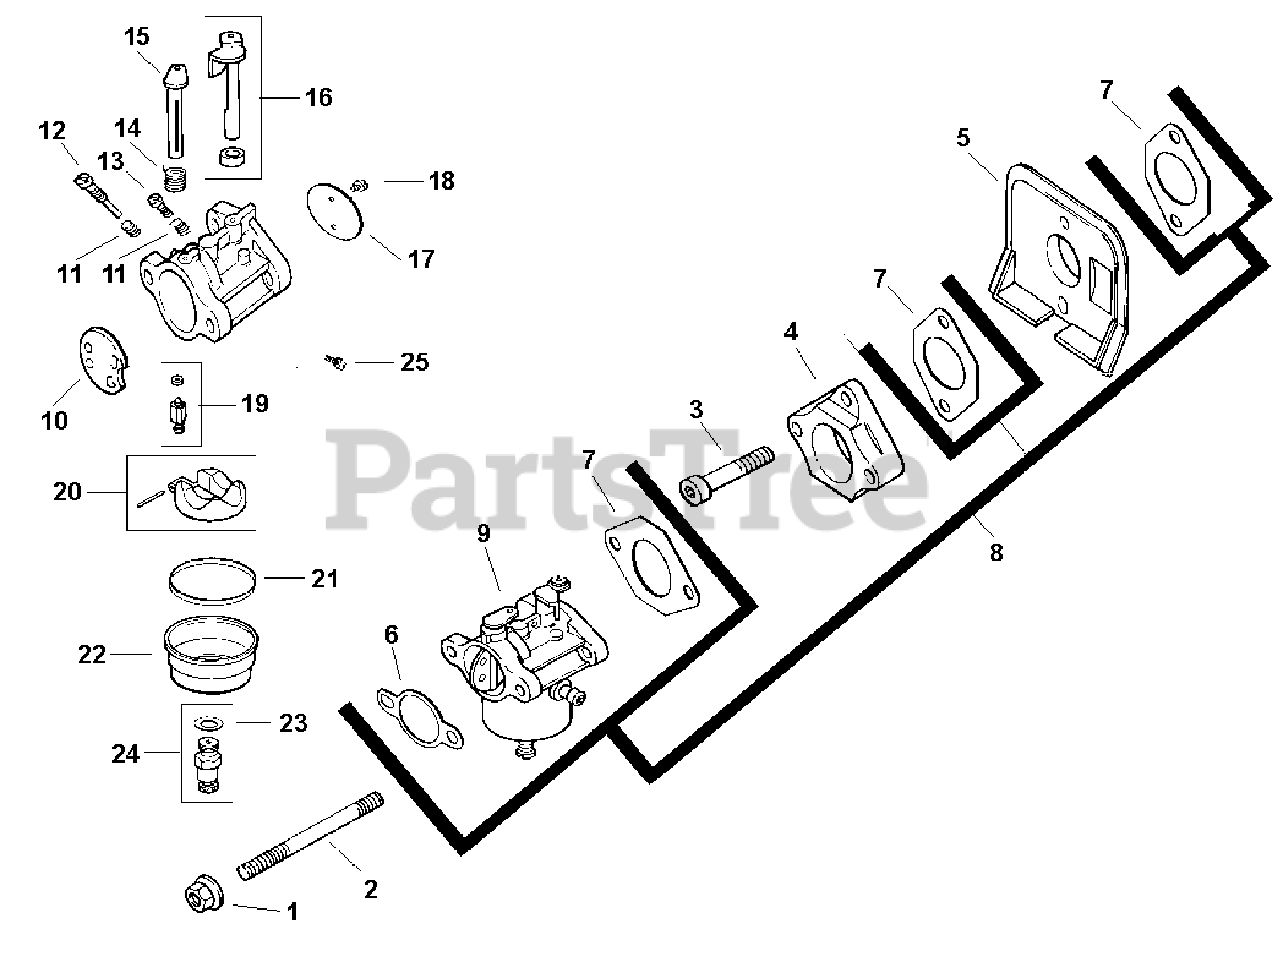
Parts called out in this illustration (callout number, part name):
1	Nut, hex. flange M6x1.0
2	Stud, carburetor M6x1x85
3	Screw, hex. socket cap M6x1x35
4	ADAPTER, CARBURETOR
5	DEFLECTOR - USE 12 265 04
6	GASKET, AIR CLEANER BASE
7	GASKET, CARBURETOR
